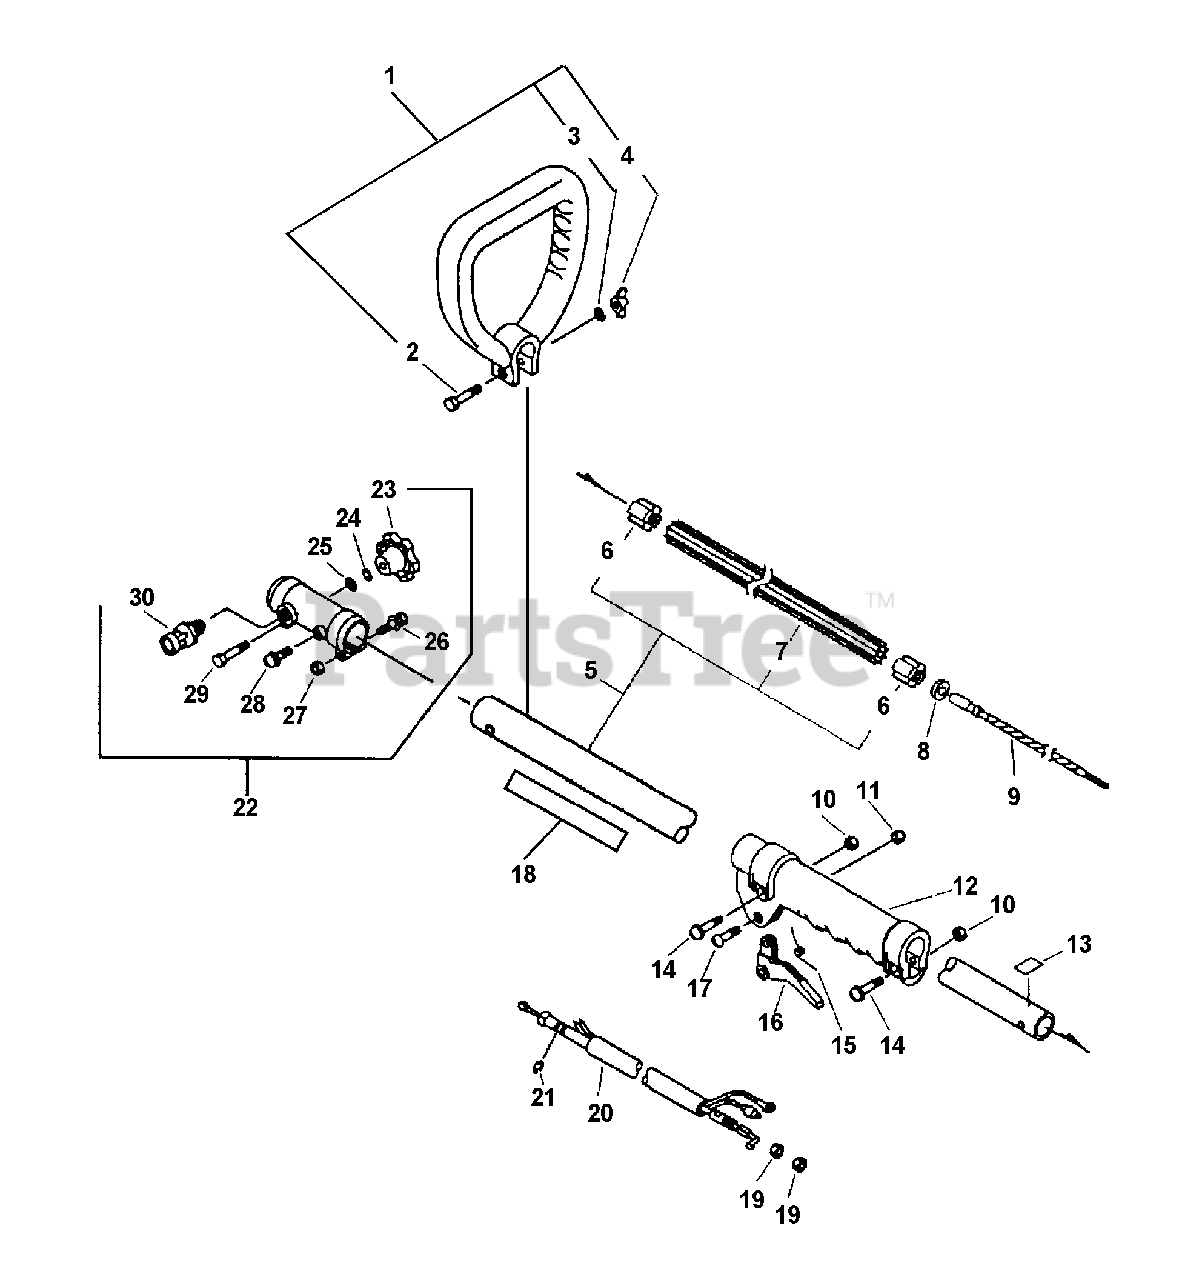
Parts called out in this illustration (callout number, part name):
1	HANDLE ASSY - FRONT
2	BOLT - 1/4-20 X 1-1/2"
3	WASHER - 1/4"
4	WINGNUT - 1/4-20
5	MAIN PIPE ASSY
7	LINER - FLEXIBLE
9	DRIVESHAFT - FLEXIBLE -- UPPER
11	LOCKNUT - 5
12	GRIP, HANDLE
13	LABEL - ALIGNMENT
14	SCREW - 5X25
15	SPRING, TRIGGER
16	TRIGGER, THROTTLE
17	SCREW - 5X30
18	LABEL - CAUTION -- SPANISH
20	CABLE, THROTTLE
21	RING, RETAINING - 4
22	CLAMP, MAIN PIPE
23	KNOB, FASTENER
24	LOCKWASHER - 5
25	WASHER - 5
26	SCREW - 5X30
28	SCREW - 5X12
29	BOLT - 5X35
30	LATCH ASSY
